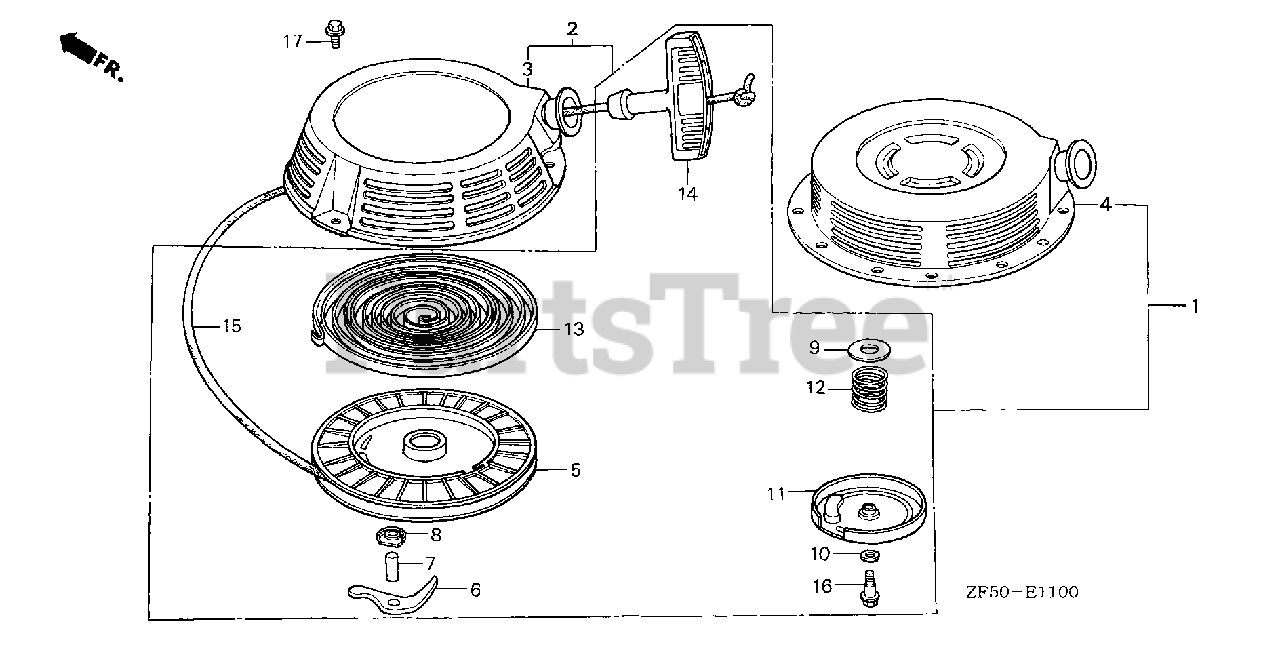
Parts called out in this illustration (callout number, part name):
2	STARTER ASSY., RECOIL *R8* Use up to Engine SN 2013098.
3	CASE, RECOIL STARTER *R8* Use up to Engine SN 2013098.
5	REEL, STARTER
6	RATCHET, STARTER
7	SHAFT, RATCHET
8	PLATE, GUIDE
9	PLATE A, FRICTION
10	PLATE B, FRICTION
11	COVER, STARTER REEL
12	SPRING, FRICTION
13	SPRING, RETURN
14	GRIP, STARTER
15	ROPE, STARTER (N/A: USE ALT P/N 08560-ZG921-11)
16	BOLT, REEL COVER
17	BOLT, FLANGE (6X10)
